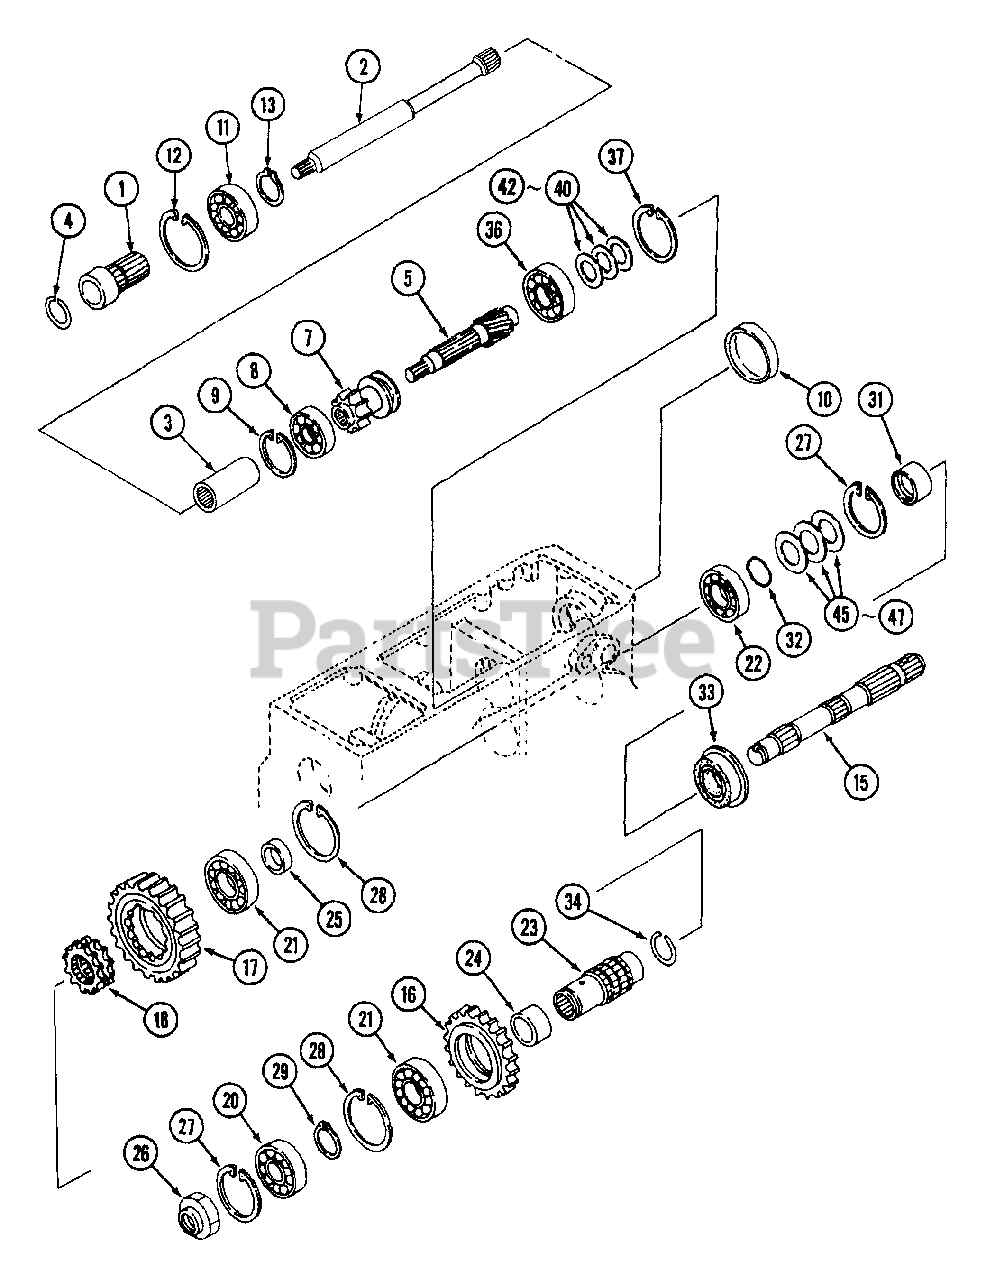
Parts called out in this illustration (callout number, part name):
3	Collar
15	Shaft, PTO Drive
29	Ring
33	Seal,Oil
